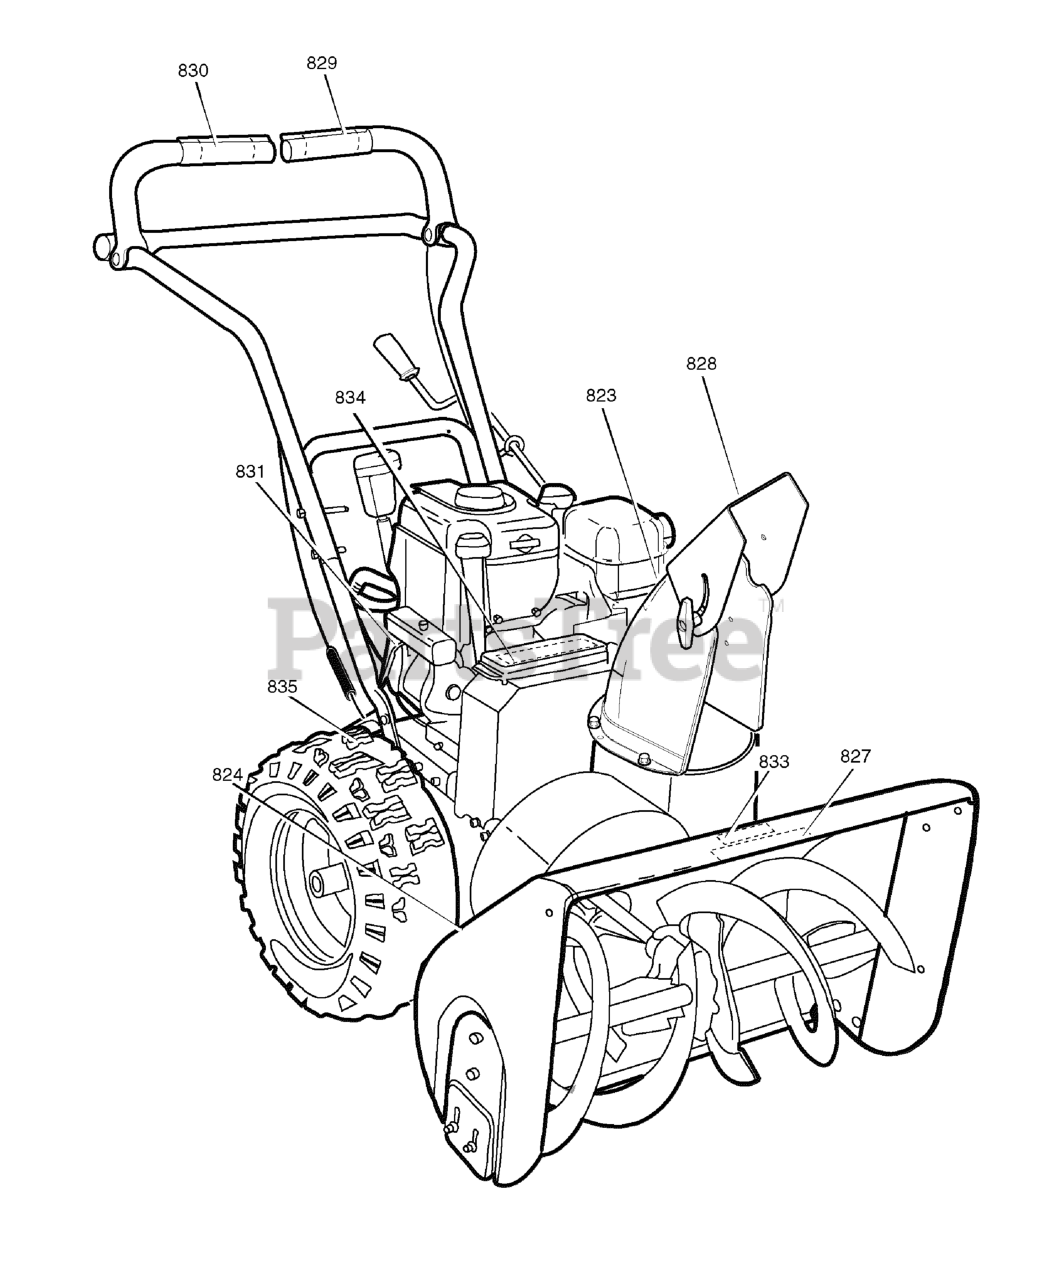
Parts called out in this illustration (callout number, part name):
823	DECAL, DANGER CHUTE HAND
824	DECAL, DANGER FOOT
827	DECAL, 1150/24 CRAFTSMAN AUGER
828	DECAL, THROWN OBJECTS
829	DECAL, DRIVE CLUTCH
830	DECAL, AUGER CLUTCH
831	DECAL, GEAR SELECTOR
833	DECAL, CLEAN & CLEAR BRUSH
834	DECAL, TOOLBOX INFORMATION
835	DECAL, ID PLATE
